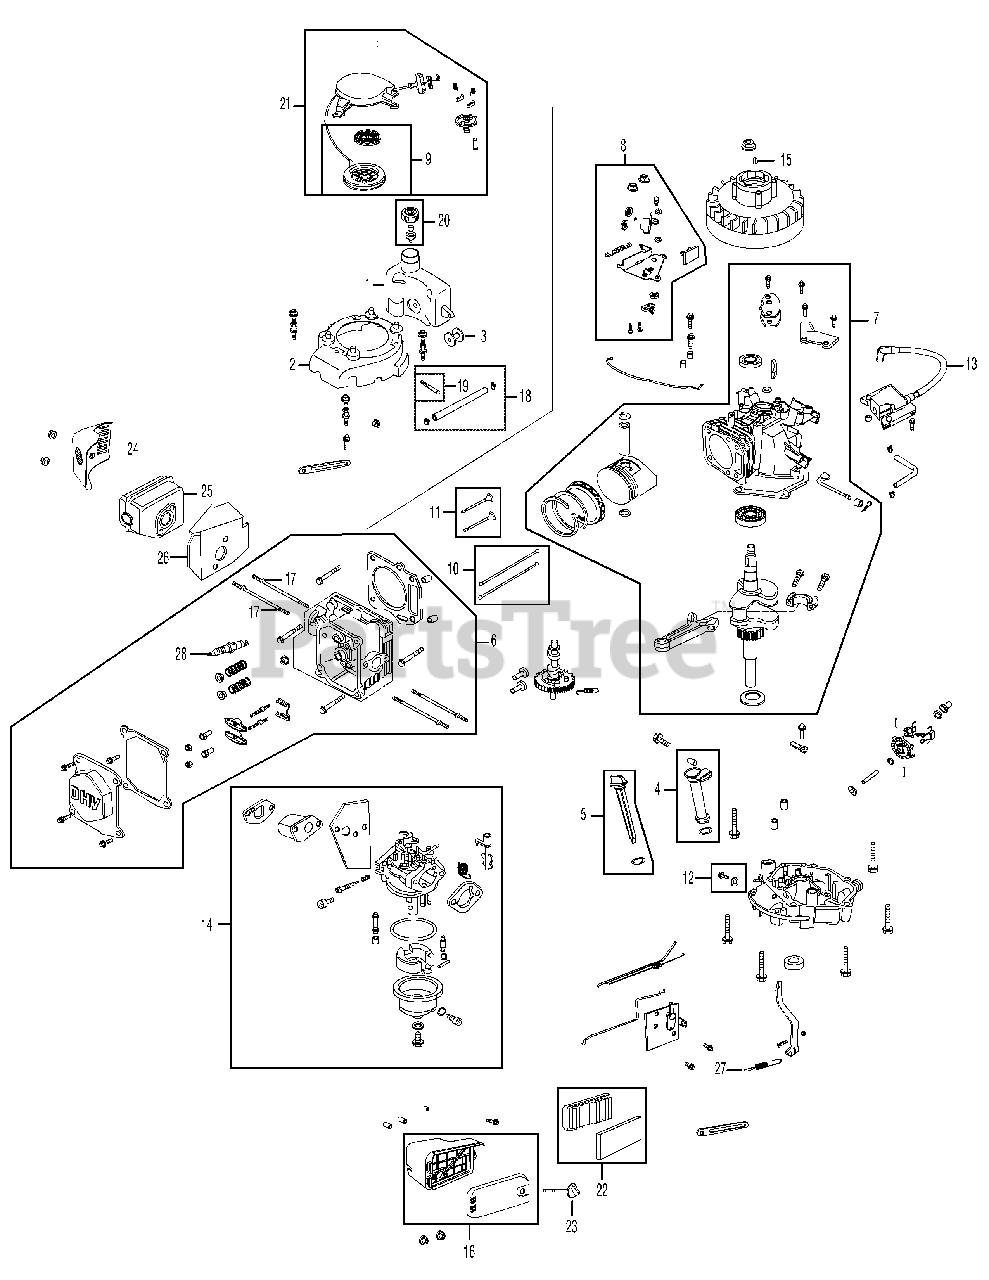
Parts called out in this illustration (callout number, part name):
1	Fuel Tank
2	Flywheel Shroud
2	Shroud Stud Left/Black
2	Shroud Stud Front/Unmarked
2	Shroud Stud Right/White
3	Rubber Fuel Tank Mounting Washer
4	Oil Filler Tube Assembly
5	Dipstick Assembly
6	Cylinder Head Complete
7	Short Block Assembly
8	Stop Switch and Brake Assembly
9	Recoil Spring and Pulley Assembly
9	Starter Shroud Stud
9	Starter Shroud Stud M6 x 79
9	Starter Shroud Stud M6 x 87-51.5
9	Nut M6
10	Push Rod Kit
10	Push Rod Guide
12	Oil Drain Plug and Washer Assembly
13	Ignition Coil
14	Carburetor Assembly
15	Flywheel Key
16	Air Cleaner Housing Assembly Complete
17	Muffler Stud Assembly
18	Fuel Line Kit - Inc. hoses, clamps & filter
19	Fuel Filter
20	Fuel Cap Assembly
21	Recoil Starter Assembly
22	Air Cleaner Kit
23	Air Cleaner Thumb Screw
24	Muffler Guard
26	Muffler Gasket /Heat Shield
27	Governor Return Spring
28	Spark Plug
